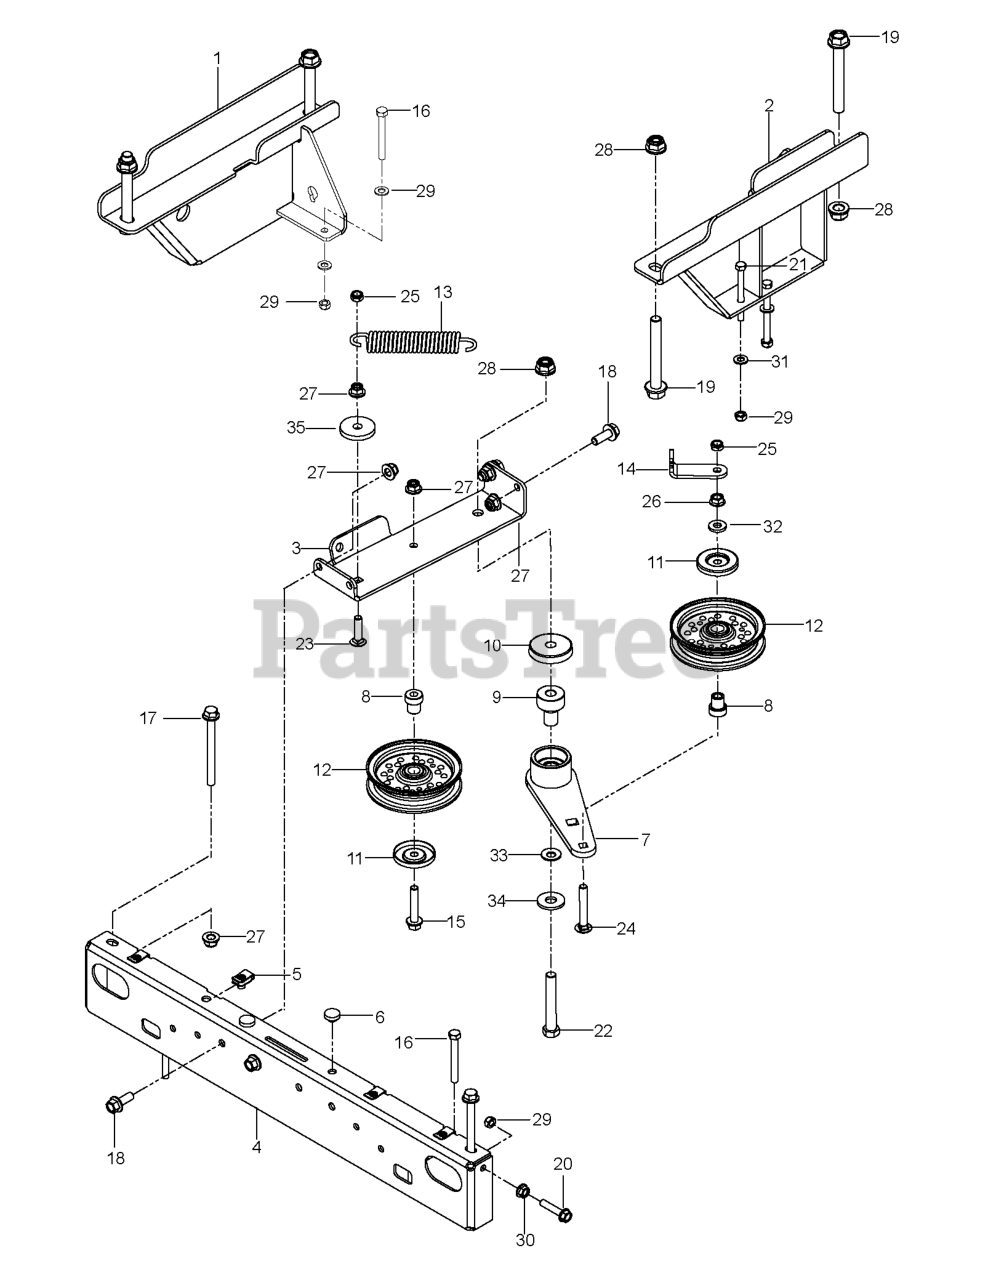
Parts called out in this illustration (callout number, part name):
1	BRACKET MTG XMSN RH BLACK
2	BRACKET MTG XMSN LH
3	MOUNT IDLER BLK
4	CROSS MEMBER XMSN BLACK
5	U-CLIP 5/16-18 NUT RETAINER
6	GROMMET, BUMPER
7	ARM, IDLER, STEEL, W/BGS
8	PIVOT, IDLER
9	PIVOT, BEARING
10	SHIELD, DUST
11	DUST SHIELD
12	IDLER PULLEY
13	SPRING, EXTENSION
14	BRACKET, SPRING
15	HHFS 3/8-16 X 2.0 GD 5
16	SCREW.5/16-18X2.5.GR8.ZY
17	HHFS 3/8-16 X 4 GR5 ZD
18	HHFS 3/8-16 X 1 GRD 5 ZD
19	HHFS 1/2-13 X 4.0 GD8 ZD
20	HHFS 5/16-18 X 1.5 GD 5
21	SCREW.5/16-18X3.GR8.ZY
22	HCS 1/2C X 3 1/4
23	RHSNB, 3/8-16 X 1-1/2
24	CARRIAGE BOLT 3/8-16 X
25	NUT HEX 3/8-16 NYLON, THIN
26	NUT 3/8C WHIZ
27	NUT 3/8-16 HEX FLG NYLOC ZD
28	NUT, 1/2-13 HEX FLG NYLOC ZD
29	LOCK.NIUT,5/16-18.GRC.ZY
30	NUT 5/16C WHIZ
31	FLAT WASHER 5/16 SAE
32	WASHER, 3/8 THICK
33	CONTACT BELLSPR 1/2
34	WASH USS FLAT 1/2
35	SPINDLE WASHER
